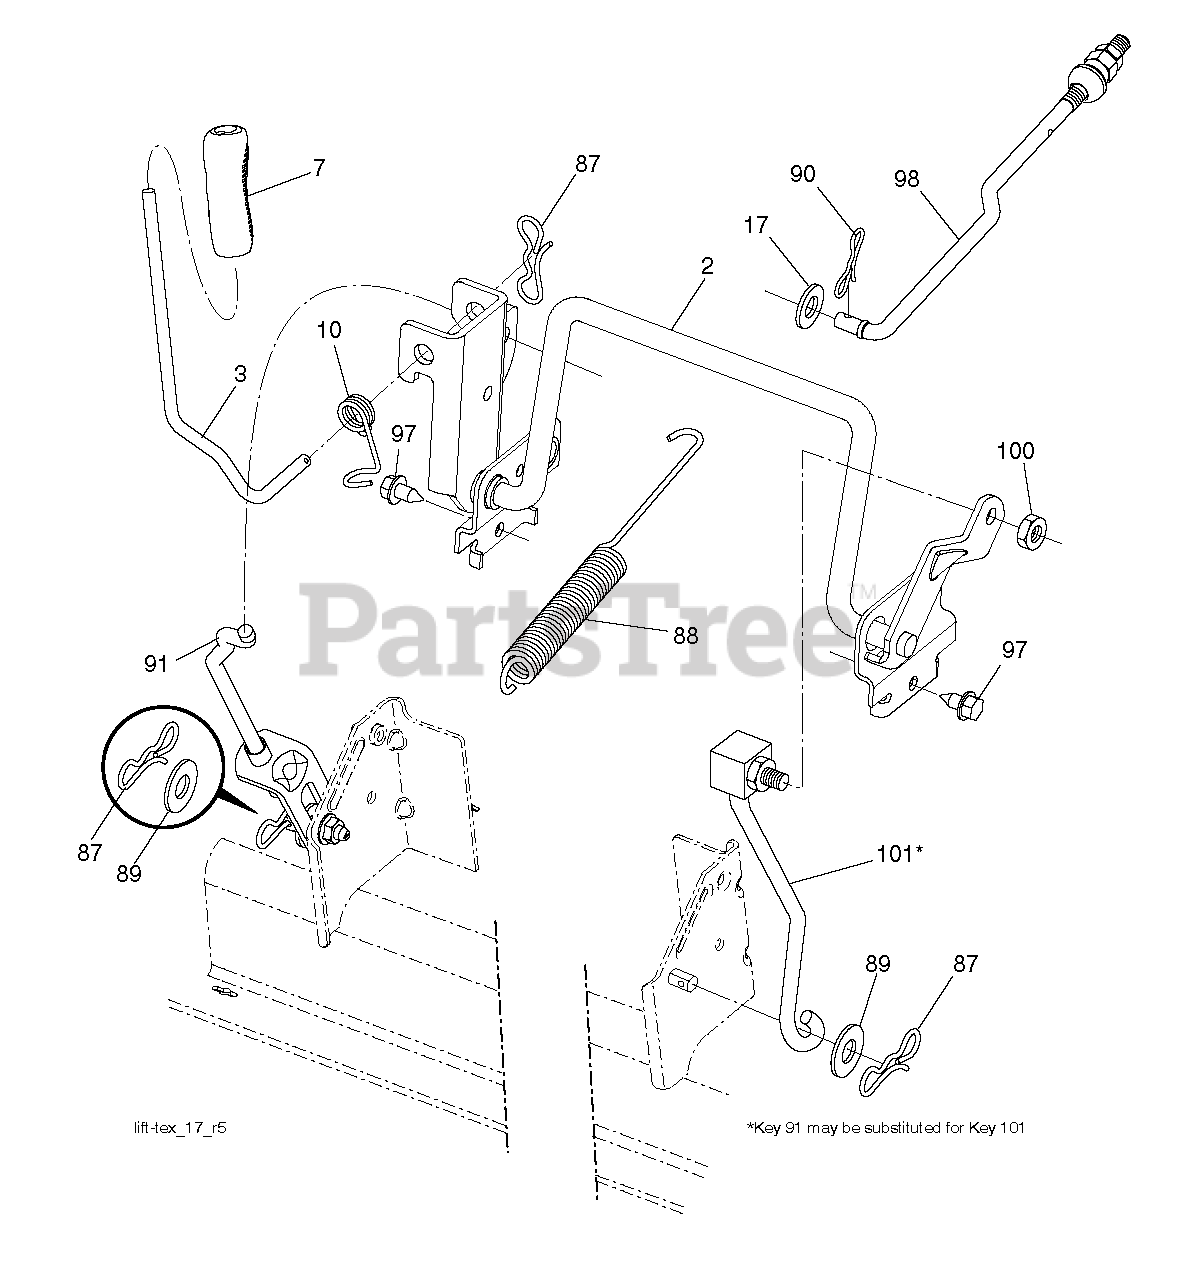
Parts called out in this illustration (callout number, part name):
3	LEVER.LIFT.HANDLE.LT
10	PLUNGER BUT KIT
17	WASHER
87	PIN.COTTER.7/16.BOW TI
89	WASHER.CLEAR.ZINC
90	PIN.COTTER.5/16.BOW TI
91	LINK.ASM.LIFT.REAR
98	LINK.ASM.SUSP.FRONT.MW
100	LOCKNUT
101	LINK.ASM.LIFT.FIXE.38/42/46"
